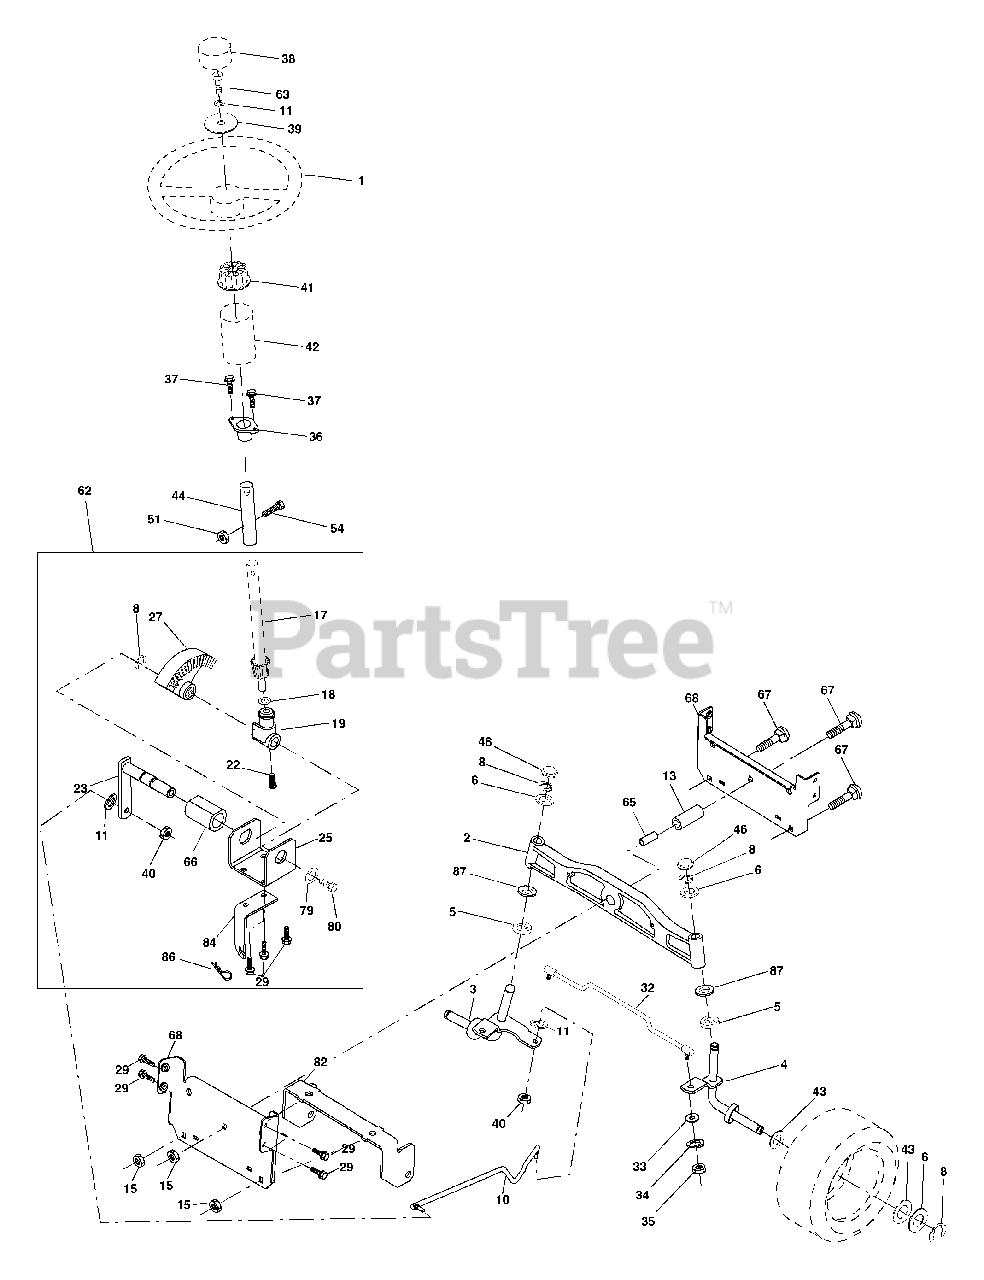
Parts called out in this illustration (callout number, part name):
1	Steering Wheel
2	Axle Asm Cast Iron Lt
3	Spindle Assembly, L.H.
4	Spindle Assembly, R.H.
5	Bearing, Race, Thrust, Hardened
6	Washer 25/32 x 1-5/8 x 16 Gauge
8	Ring, Klip
10	Link, Drag
11	Washer, Lock
13	Spacer Brg Axle Front
15	Nut Hex Flange Lock
17	Shaft Assembly, Steering
18	Washer, Thrust .515 x .750 x .033
19	Support, Shaft
22	Screw Hex Wshhd Torx
23	Pittman Shaft Assembly
25	Bracket, Steering
27	Gear, Sector
29	Screw 3/8-16 x 3/4
33	Washer 11/32 x 3/4 x 16 Ga.
34	Washer Lock Hvy Hlcl Spr 5/16
35	Crownlock Nut 5/16-24 Unf 3847
36	Bushing, Steering
37	Screw TT #I0-32 x 5 x 3/8 Flange
38	Cap Wheel Steering
39	Washer 13/32 x 1-1/20 x 11 Gauge
40	Nut Lock Center 3/8-24 Unf
41	Adaptor, Steering Wheel
42	Boot, Steering Dash P/L Mtl
43	Washer 25/32 x 1-1/4 x 16 Gauge
44	Extension Steering Non-Adjust
46	Cap, Spindle
51	Nut Lock Hx W/Ins 5/16-18 UNC
54	Bolt Fin Hex 5/16-18 UNC x 1-1/4
62	Kit, Steering Assembly, Service
63	Bolt Fin Hex 3/8-16 unc. x 1 Gr. 5
65	Spacer Brace Axle
66	Bearing Arm Pittman
67	Bolt Rdhd Sq 3/8-16 x 2-1/4
68	Brace Axle
79	Washer 13/32 x 1-1/4 x 12 Ga
80	Bolt Hex Nylon 3/8-16 x 3/4
82	Bracket Susp Chassis Front
84	Bracket Cable Clutch Chassis
86	Retainer Spring
87	Washer Flat .781 x 1 1/2 x .14
